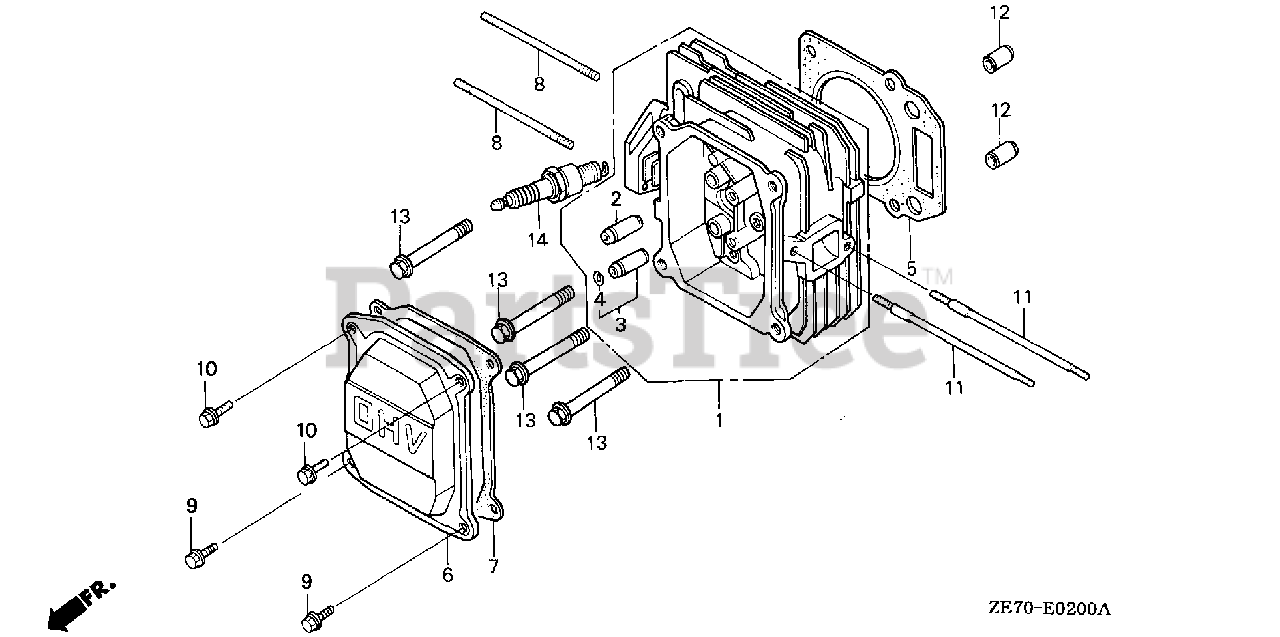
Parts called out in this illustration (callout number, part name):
1	CYLINDER HEAD
2	GUIDE, VALVE (OS)
3	GUIDE, EX. VALVE (OS)
4	CLIP, VALVE GUIDE
5	GASKET, CYLINDER HEAD
6	COVER, HEAD
7	GASKET, CYLINDER HEAD COVER
8	BOLT, STUD (6X85)
9	BOLT, FLANGE (6X12) (CT200)
10	BOLT, FLANGE (6X12) (CT200)
11	BOLT, STUD (6X109)
12	PIN A, DOWEL (10X16)
13	BOLT, FLANGE (8X50)
14	SPARK PLUG (BPR4ES) (NGK)
14	SPARK PLUG (W14EPR-U) (DENSO)
14	SPARK PLUG (BPR5ES) (NGK)
14	SPARK PLUG (W16EPR-U) (DENSO)
14	SPARK PLUG (BPR6ES) (NGK)
14	SPARK PLUG (W20EPR-U) (DENSO)
